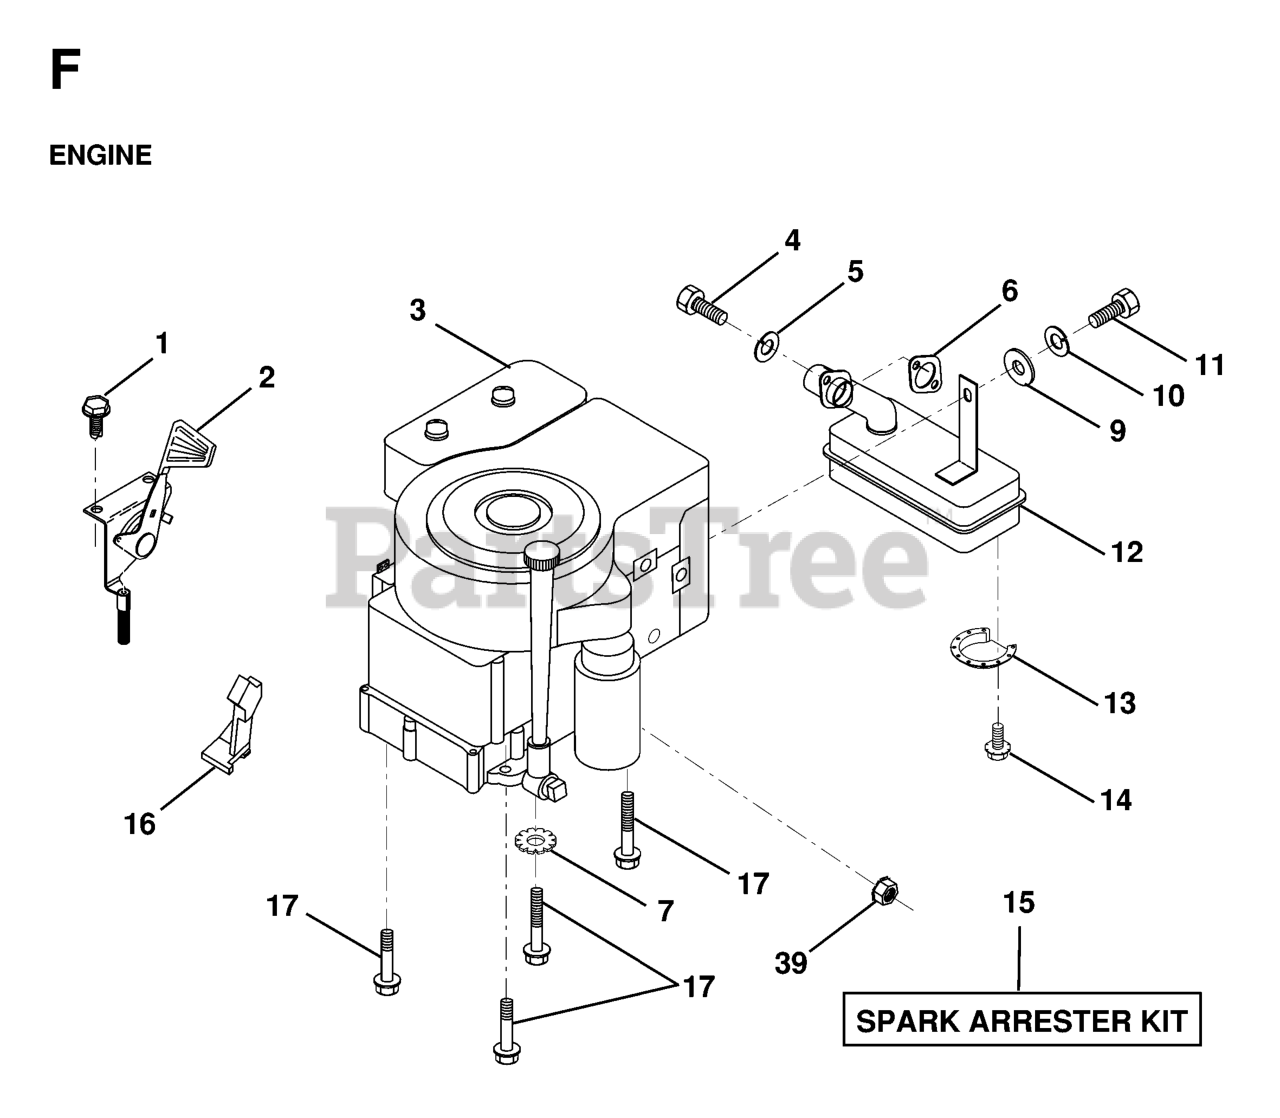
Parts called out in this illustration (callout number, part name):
2	CONTROL.TH/CH.RH.BLK.FLG.EEC
4	SCREW
5	WASHER.LOCK.HVY.HLCL.SPR.5/16
6	GASKET.ENG.1.313 ID.TIN PLATED
7	LOCKWASHER
9	WASHER
10	LOCKWASHER
12	MUFFLER.SINGLE.B&S.12HP
13	DEFL MUFFLER LTV
14	SCREW
15	KIT.SPARK ARRESTOR 794945 B&S
16	STOP THROTTLE
17	SCREW LT
39	NUT FLANGE 1/4-20 STARTER NUT
